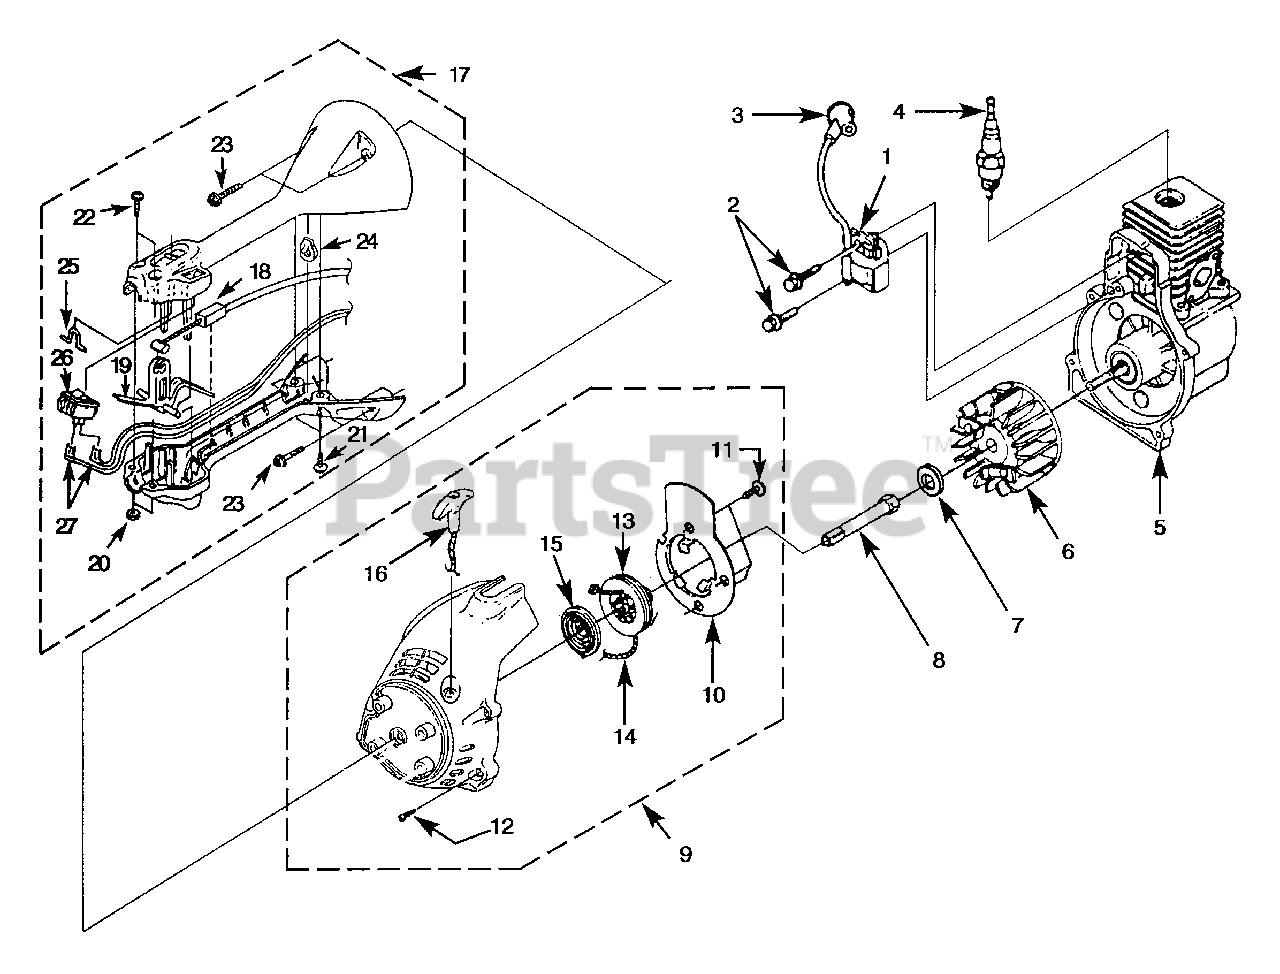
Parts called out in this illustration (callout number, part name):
1	MODULE-Ignition
2	TERMINAL & COVER
3	SCREW-Taptite (8-32 X 1")
4	SPARK PLUG
5	SHORT BLOCK
6	ROTOR w/Starter Pawls
7	WASHER-Flat (5/16)
8	CONNECTOR-Drive
9	STARTER ASSEMBLY
10	PLATE-Baffle
11	SCREW-Plastite (8-16 X 5/8")
12	SCREW-Thread Form. (10-24 X 3/4")
13	PULLEY-Starter
14	ROPE-Starter (42")
15	SPRING & CONTAINER
16	GRIP-Starter
17	CONTROL HANDLE
18	CABLE-Throttle
19	TRIGGER
20	NUT-Hex (#10-24)
21	SCREW-Plastite (#10-14 X 7/8")
22	SCREW-Machine (#10-24 X 1 1/4")
23	SCREW-Plastite (#10-14 X 1 1/8")
24	STOP-Drive Shaft
25	HOOK-Strap
26	SWITCH-Rocker
27	LEADS-Electrical
